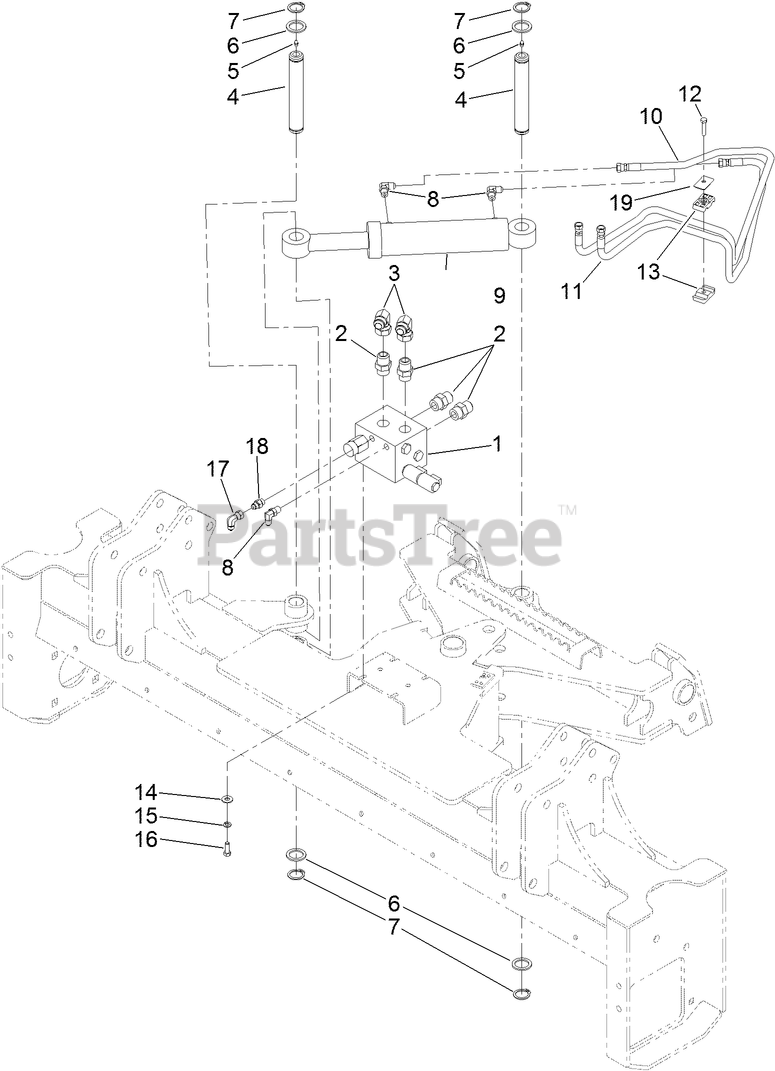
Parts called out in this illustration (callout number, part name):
1	HYDRAULIC MANIFOLD ASM
2	FITTING-ADAPTER
3	FITTING-ELBOW, 90
4	PIN-PIVOT
5	FITTING-ZERK
6	WASHER
7	RING-RETAINING, EXTERNAL
8	FITTING-ELBOW
9	HYDRAULIC CYLINDER ASM
10	HOSE-HYD
11	HOSE-HYD
12	SCREW-HH
13	CLAMP-TUBE
14	WASHER-FLAT
15	WASHER-LOCK
16	SCREW-HH
17	ELBOW-SWIVEL, 90 DEG
18	FITTING,STRAIGHT,6-MORB X 6-M37JIC
19	COVERPLATE
20	HARNESS-WIRE
